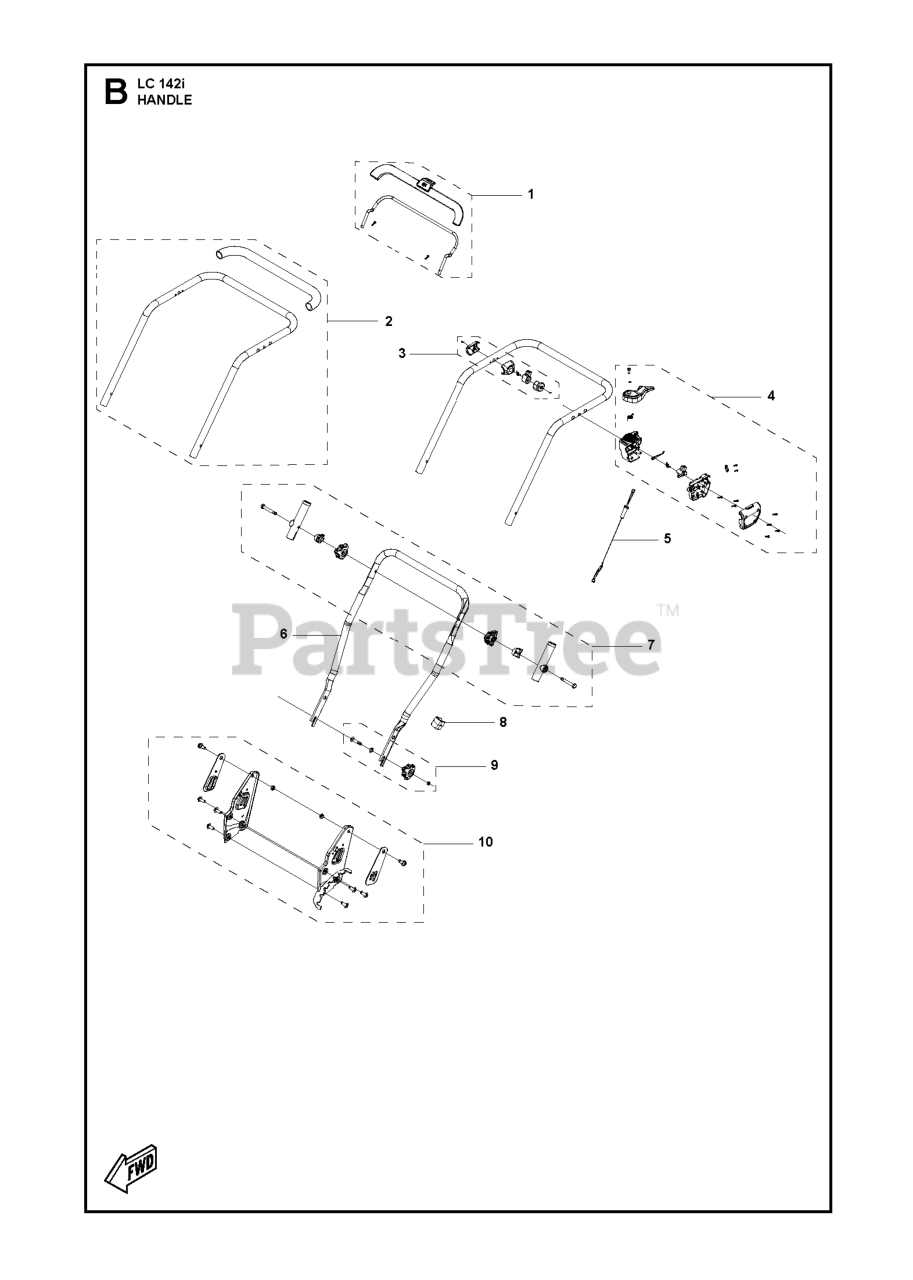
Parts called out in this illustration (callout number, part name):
2	SQUARE KEY
15	WASHER
17	SPRING.BRAKE.K46.GREEN
26	SPRING.RETURN.CRUISE
29	ROD.BRAKE.K46
35	ROD .BRAKE. PARKING. GT. HUSQ.
42	PEDAL COVER T
50	IDLER.FLAT.910.OFFSET
51	NUT LOCK FLG 3/8-16 UNC
52	IDLER.V-GROOVE.910.OFFSET
56	V-BELT.MOWER.92.40.42/K46
64	SHAFT.ASM.PEDAL.BRK.CNTR
80	STRAP.TORQUE.K46.K57R.TT
92	BOLT
99	ROD.SPRING.BYPASS.K46.LT.Z
116	NUT LOCK HEX FLANGE 5/16-18
125	SCREW
143	Screw 5/16-18 x 1/2 Hex, Self Tapping 5/16-18 x 1/2
153	RETAINER M
159	COTTER PIN
160	RETAINER CLIP
161	SPRING, RETURN LT
163	ROD.CONTROL.K57R.K46
166	NUT.PUSH.625
167	LATCH.BRAKE.SPRING
170	KEEPER.V-IDLER.CENTER.
183	SPACER AXLE
184	RB HANDLE.PARKG.BRK.HUS/PRED
186	SPACER.RETAINER
187	WASHER 12/32X2X10GA
188	RP.LINK.CLUTCH.GROUND.DRIVE
189	BELLCRANK.GROUND.DRIVE.TEX.
190	KEEPER.BELLCRANK.DRIVE
206	BRACKET.MOUNT.CRUISE.LATCH
207	LATCH.CONTROL.CRUISE
208	GEAR.SECTOR.CONTROL.CR
209	ROD.CONTROL.CRUISE.GT.
210	ROCKER.ASM.PEDAL.CONTR
211	BEARING.NYLON
213	KNOB.CONTROL.CRUSIE.HU
214	PEDAL.FORWARD.PAD.TEX
215	PEDAL.REVERSE.TEX.GT.4
216	BRACKET.PULLEY.IDLER.W/TEX
221	RETAINER.SPRING.CLIP.H
222	WASHER 21/32 X 1-1/4 X 10 GA.
225	KEEPER.BELT.TRANSAXLE.K46
226	BRACKET.MOUNT.TORQUE.K46.TLT
227	SCREW.THDROL.5/16-18X3/4.TTY
230	WASHER.HARDENED
